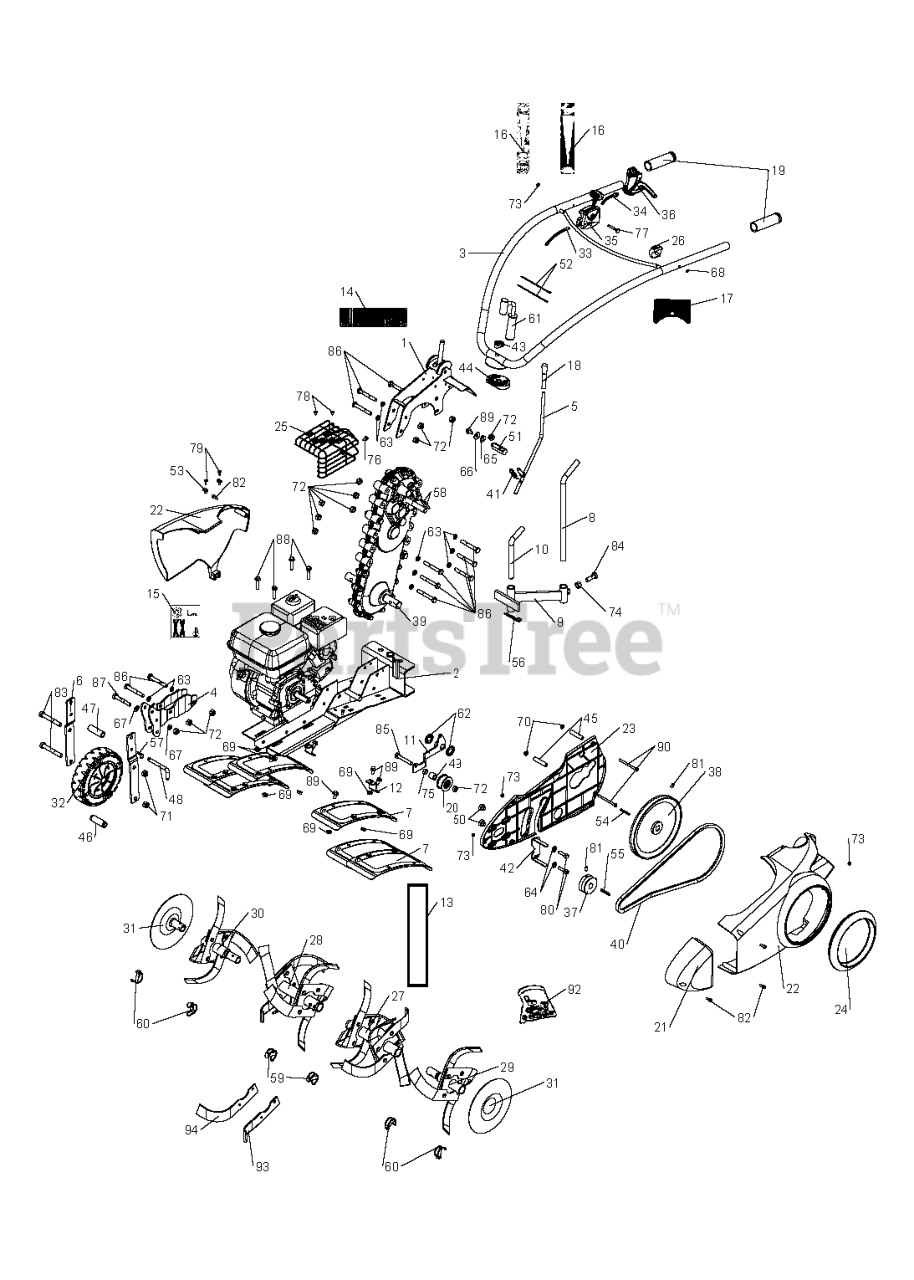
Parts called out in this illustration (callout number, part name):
6	WHEEL BRACKET
17	LABEL
20	PULLEY
41	SPRING LOCKING
43	SPACER
47	SPACER 0302020070
55	SCREW
57	COTTER PIN
62	WASHER
66	WASHER
67	WASHER 0300401003
69	NUT
70	NUT
72	NUT
73	Blocking nut M 6 Z
74	NUT 0300201202
75	NUT
79	SCREW
81	SCREW
83	SCREW 0300011213
86	SCREW
88	SCREW
92	HOLDER
